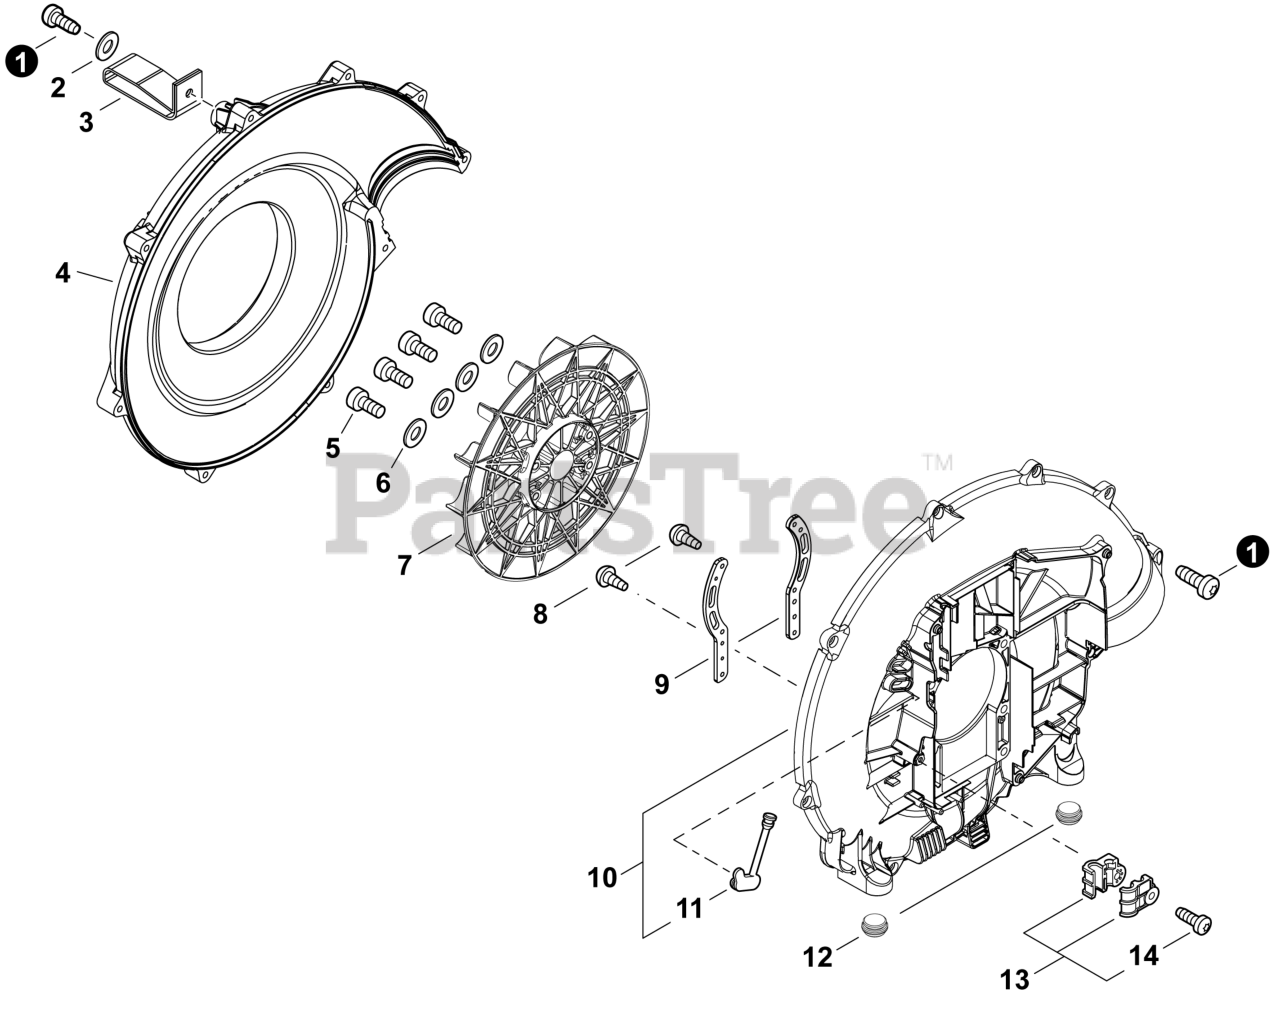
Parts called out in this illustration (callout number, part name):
1	BOLT, TORX 5x20
2	WASHER 5.5x16x2T
3	STRAP, SAFETY
4	FAN COVER, PB-580
5	BOLT, TORX 5x30
6	WASHER 5.5x16x2T
7	FAN, BLOWER
8	SCREW, TAPPING 3x12
9	BRACKET, ENGINE
10	CASE KIT, FAN
11	GROMMET
12	CUSHION
13	CABLE HOLDER SET
14	BOLT, TORX 5x25
